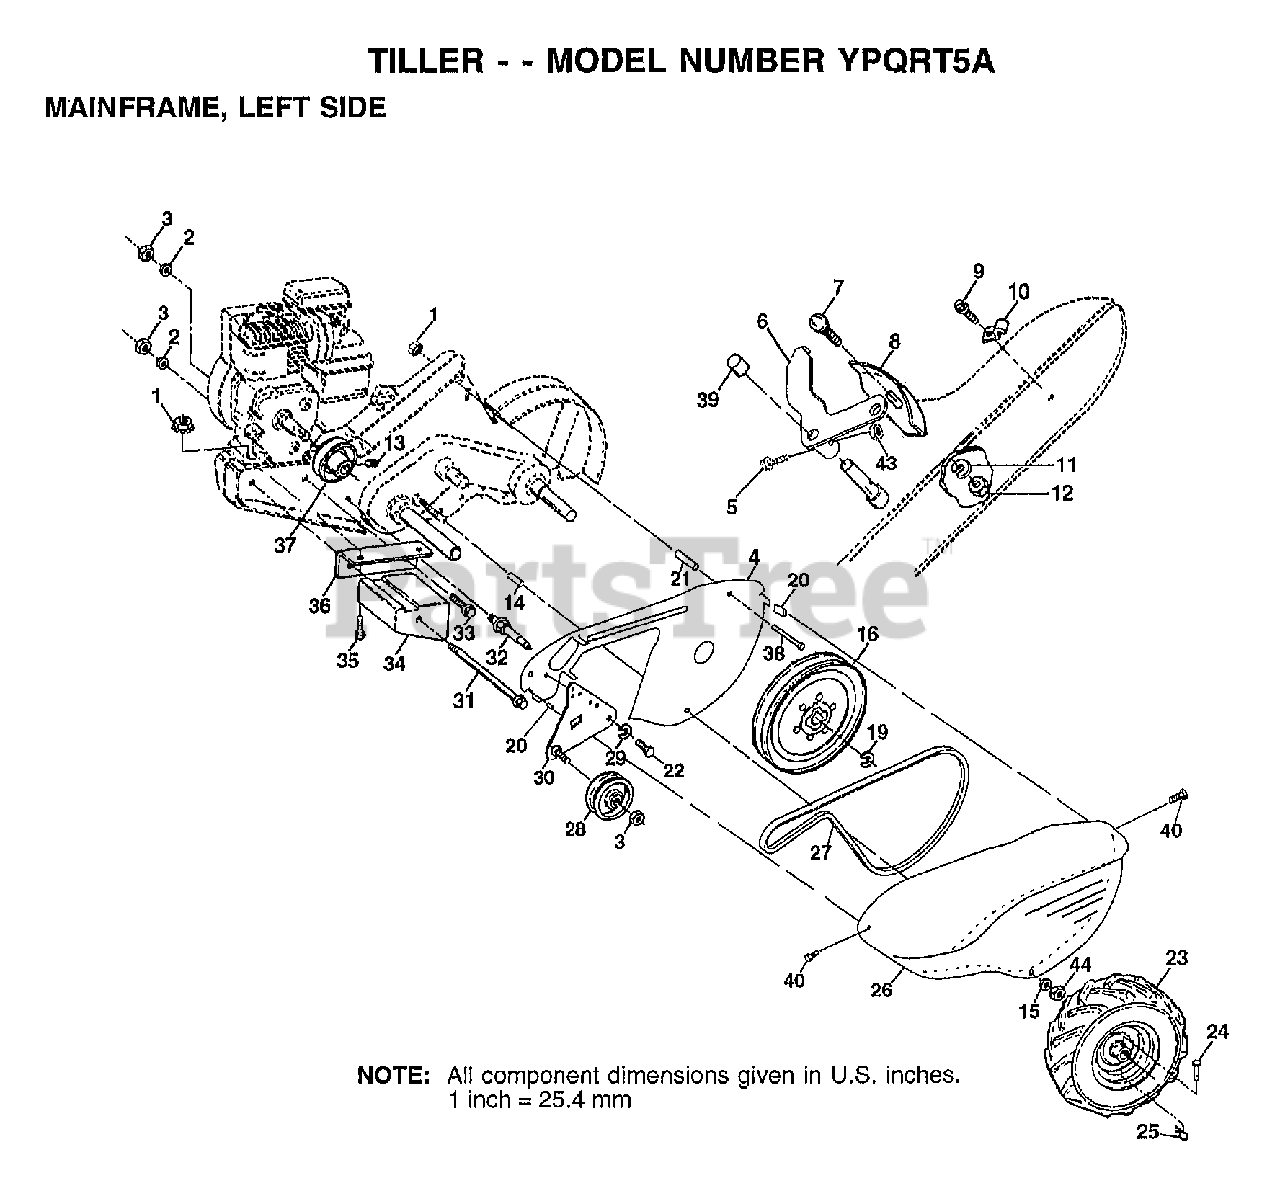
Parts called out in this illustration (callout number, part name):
2	LOCKWASHER
3	NUT.HEX.3/8-16UNC
4	SHIELD.INNER.BELT
5	"SCREW-LEVER,SHI"
6	LEVER ASM CRT
7	BOLT
8	PANEL TI
10	CONDIUT CLIP T
11	LOCKWASHER
13	SET SCREW
14	SPACER-SPLIT
15	WASHER
16	SHEAVE.TRANS.
20	NUT J CLIP #8
21	SPACER CRT
22	BOLT.FIN.HX.5/16-24X1/2
23	TIRE.CHV.13X5.0-6
24	RIVET.DRILL.1.75
25	RETAINER M
26	GUARD.BELT
27	BELT-V
28	PULLEY-IDLER TI
29	KLIP RING
30	BRACKET ASM IDLER
31	BOLT CRT
32	SHIFT ARM CRT
33	BOLT
34	COUNTERWEIGHT CRT
35	BOLT.HEX.5/16-1.5
36	BRACKET LH CRT
37	ENGINE PULLEY
39	CAP PLUNGER BLACK
40	SCREW HX WSH.HD#8-18X1/2
43	LOCKNUT
44	NUT
